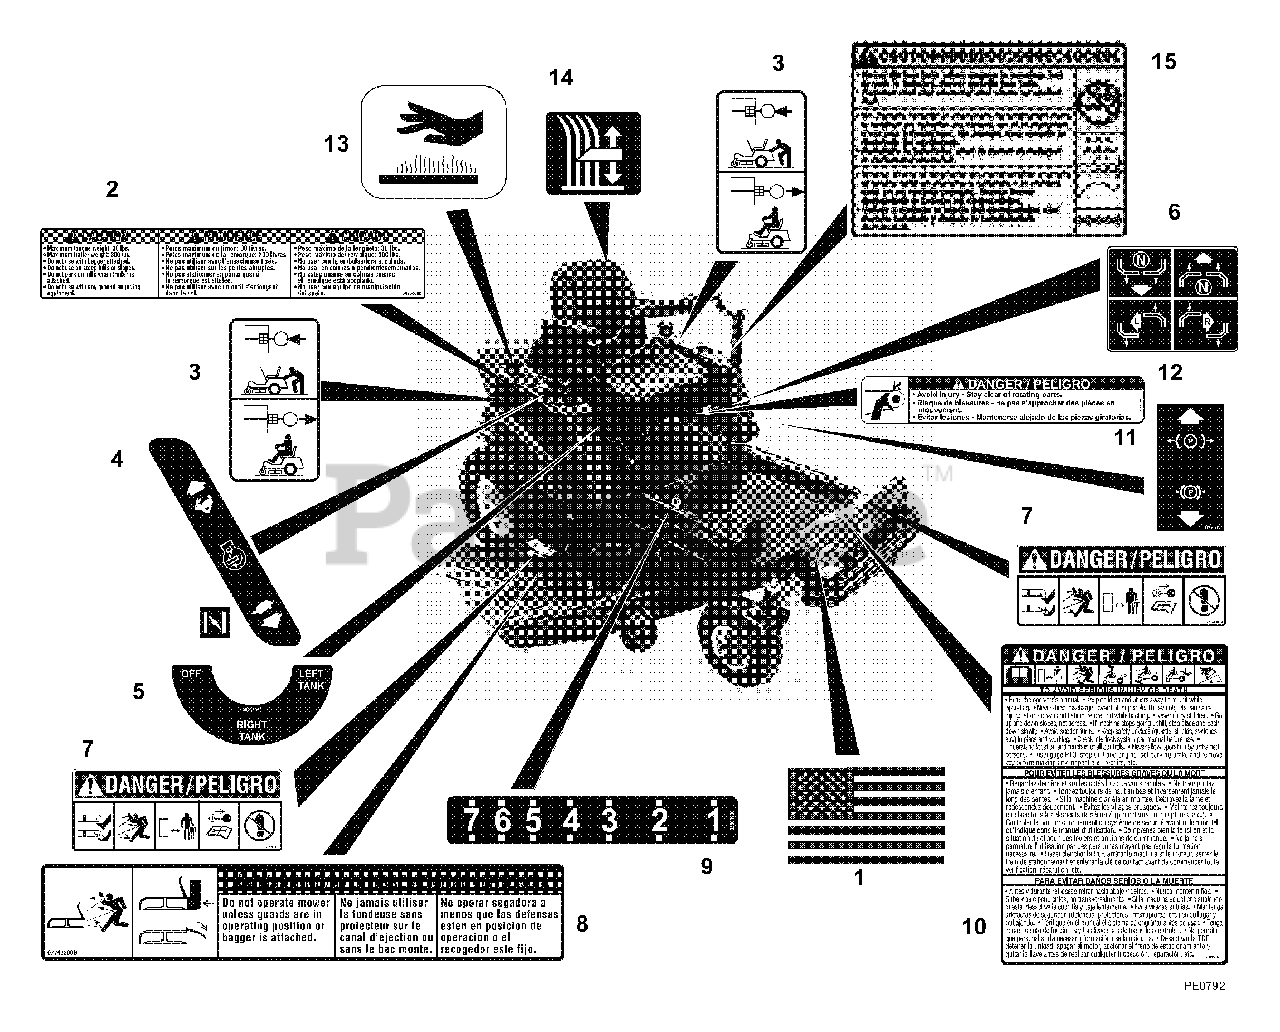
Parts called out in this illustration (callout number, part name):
1	DECAL, AMERICAN FLAG
2	DECAL, TRAILER HITCH
3	DECAL, TRANSMISSION DISCONNECT
4	DECAL, SPEED CONTROL
5	DECAL, FUEL VALVE
6	DECAL, INSTRUCTIONAL-STEERING
7	DECAL, MOWER PAN DANGER
8	DECAL, WARNING
9	DECAL CUT HEIGHT
10	DECAL, DANGER BILINGUAL
11	DECAL, PARKING BRAKE LEVER
12	DECAL- DANGER
13	DECAL, HOT SURFACE
14	DECAL-CUT HEIGHT
15	DECAL,FUEL WARNING
